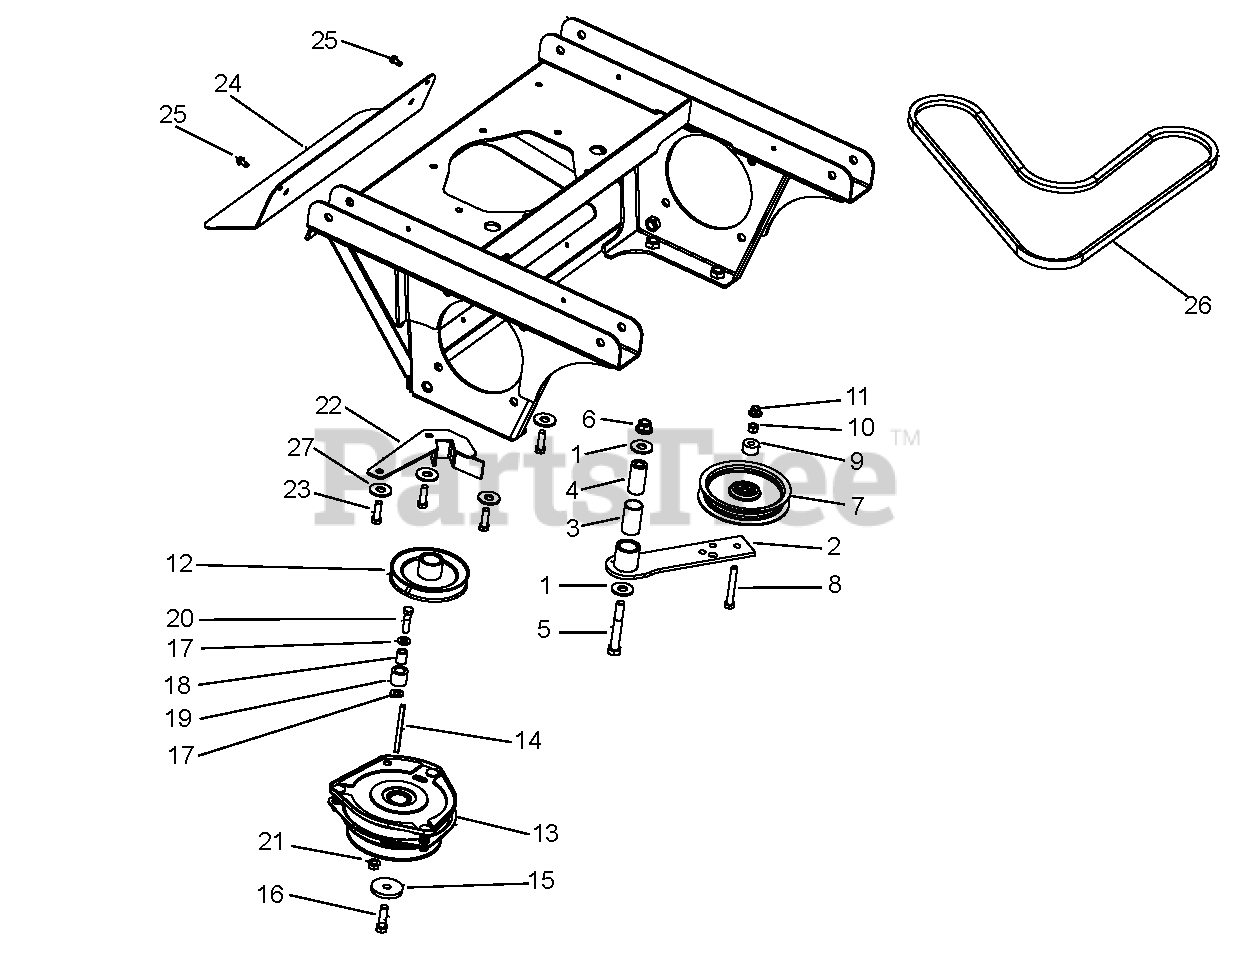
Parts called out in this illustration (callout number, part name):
1	Washer, Flat Steel.563 x 1.38 x .109YWZC
2	Weldment, Idler Arm Ground Drive
3	Bushing, 1.00 x 1.125 x 1.937
4	Bushing, Spacer .502 x .997 x 2.03 PM
5	Bolt, Hex .50-13 x 3.50 GR5 YWZC
6	Nut, Locking Nyloc Flange .50-13 YWZC
7	Idler, Flat 5.00 x .38
8	Bolt, Hex .38-16 x 2.75 GR5 YWZC
9	Spacer .390 x 1.000 x .562
10	Nut, Locking Center .38-16 YWZC
11	Nut, Locking Nyloc Flange .38-16 YWZC
12	Sheave, Engine 5.426 x 1.127
13	Clutch, Electric-OGURA GT3.5-VP01R
14	Key, Square .25 x 3.50 x .25 SAE
15	Washer, Flat Steel .469 x 2.00 x .25 YWZC
16	Bolt, Hex .44-20 x 1.50 G5 YZ EP80
17	Washer, Flat Steel. 406 x .812 x .065 YWZ
18	Bushing, S.407 x .625 x .813 ST
19	Bumper, Rubber .62 x 1.0 x .88 LG
20	Bolt, Hex .38-16 x 1.50 GR5 YWZC
21	Nut, Locking Top Flange .38-16 YWZC
22	Weldment, Clutch Stop
23	Bolt, Hex .38-16 x 1.25 G5 NYTORQ (992200, 201, 203, 197, 198)
24	Shield, Muffler Heat
25	Screw, Tap .25-20 x .50 Hex Washer Head TR YWZ
26	V-Belt, Cogged B-Raw Edge
27	Washer, .38 Spring Disc (992000, 201, 203, 197, 198)
